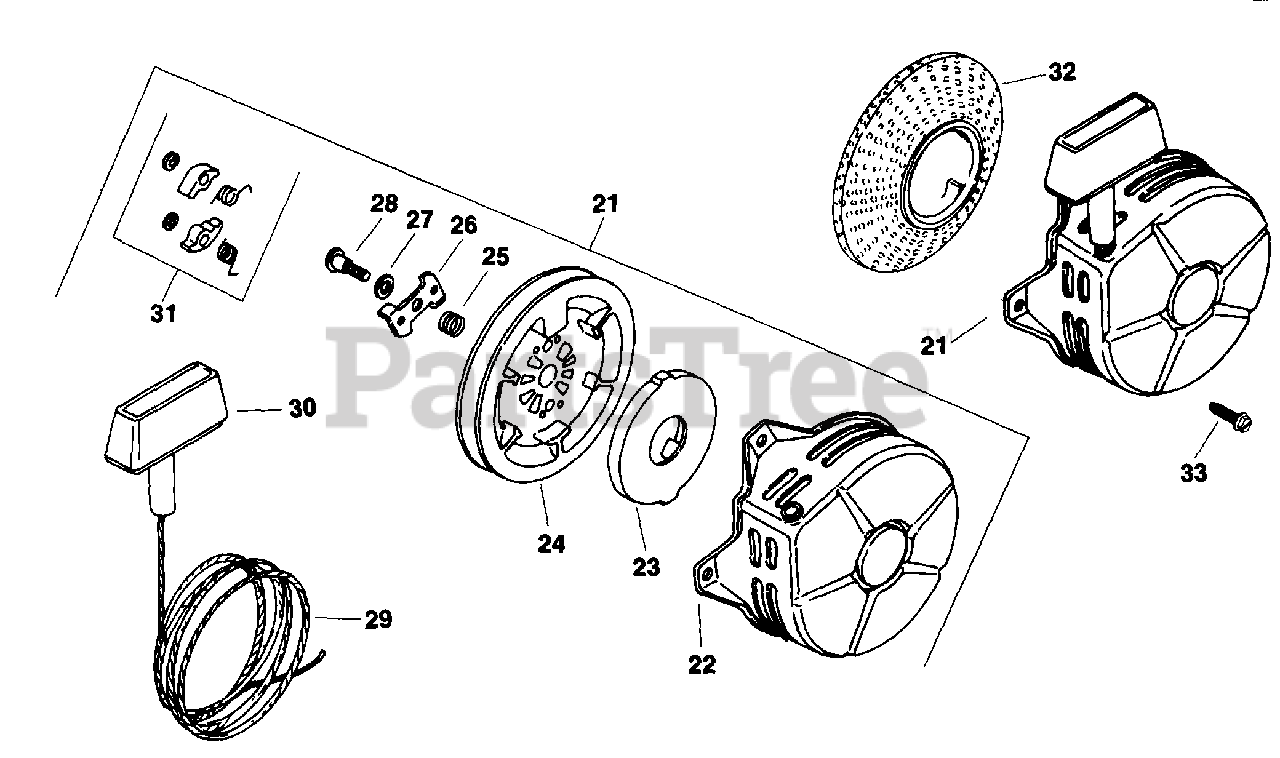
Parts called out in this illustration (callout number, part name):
21	STARTER - USE 41 755 26
22	HOUSING - DISCONTINUED
23	SPRING & KEEPER ASSEMBLY - DISCONTINUED
25	SPRING - DISCONTINUED
26	CAM - (#DSC)
28	SCREW - DISCONTINUED
29	ROPE - USE 15 160 01
30	HANDLE - USE 25 166 01
31	KIT, PAWL REPAIR - (#DSC)
32	CUP - DISCONTINUED
33	SCREW, FLG HD 10-24X1/4"
